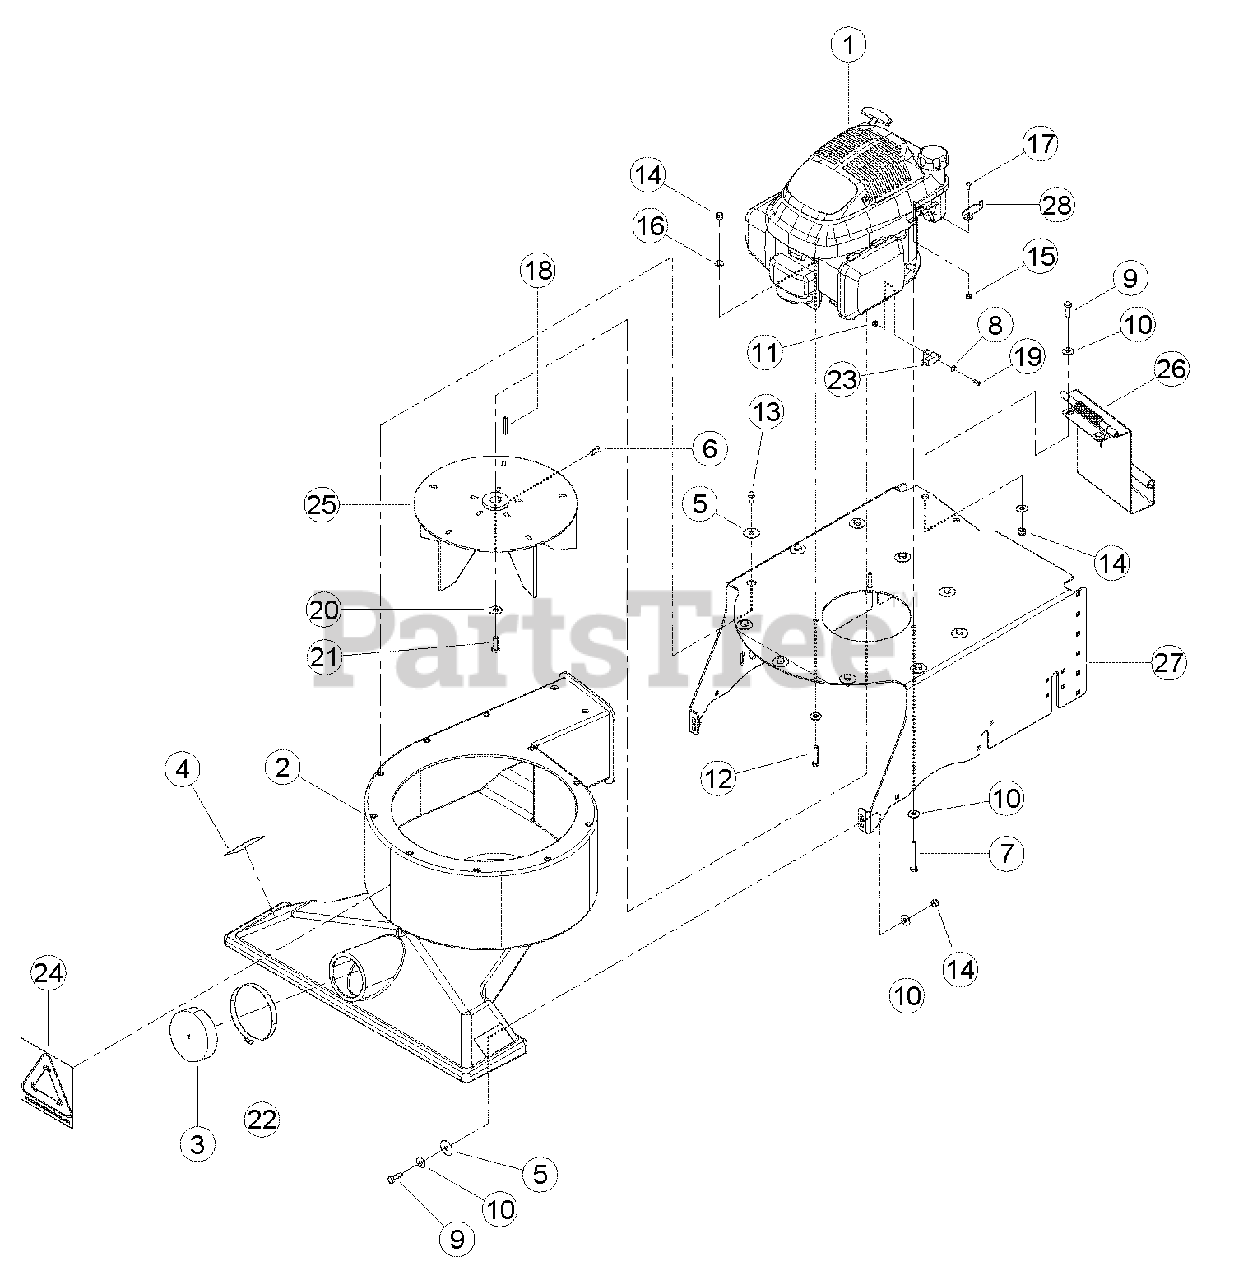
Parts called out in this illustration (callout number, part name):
1	ENGINE, 190CC B&S INTEK/IC VERTICAL (FOR SERVICE SEE ENGINE OWNER'S MANUAL OR YOUR NEAREST AUTHORIZED BRIGGS & STRATTON ENGINE DEALER)
2	HOUSING, FAN W/INTAKE
3	CAP, ROUND VINYL (4 X 1)
4	DECAL, DANGER
5	WASHER, 5/16 FENDER ZP
6	SCREW, 5/16-18 X 5/8 SQ HD SET
7	BOLT, 5/16 X 2-1/2 HEX HD GR5 ZP
8	WASHER, #8 SAE FLAT
9	BOLT, 5/16 X 1 HHCS GR5 ZP
10	WASHER, 5/16 FLAT ZP
11	NUT, #8 X 32 NYLOCK
12	BOLT, 5/16 X 1-1/2 HEX HD GR5 ZP
13	BOLT, 5/16 X 5/8 HEX HD GR5 ZP
14	NUT, 5/16 NE NYLOCK ZP
15	NUT, 10/24 NYLOCK TYPE NM, ZP
16	WASHER, 5/16 SAE FLAT ZP
17	SCREW, MCH 10-24 X 1/2 PAN HD, PH ZP
18	KEY, 3/16 SQUARE X 1-1/4 LONG PLAIN
19	SCREW, #8 X 32 X 3/4 PAN PHP ZP
20	WASHER, 3/8 GR8 USS ZP
21	BOLT, 3/8 X 1 HHCS GR5 NF ZP
22	CLAMP, 4 IN. HOSE
23	SWITCH, HONDA ENGINE KILL
24	DECAL, COLLECT IT
25	WELDMENT, BEARVAC ROTOR
26	ASSEMBLY, EXHAUST DOOR
27	SUPPORT, BEARVAC FRAME
28	PLATE, HONDA BRACKET HOLDER
